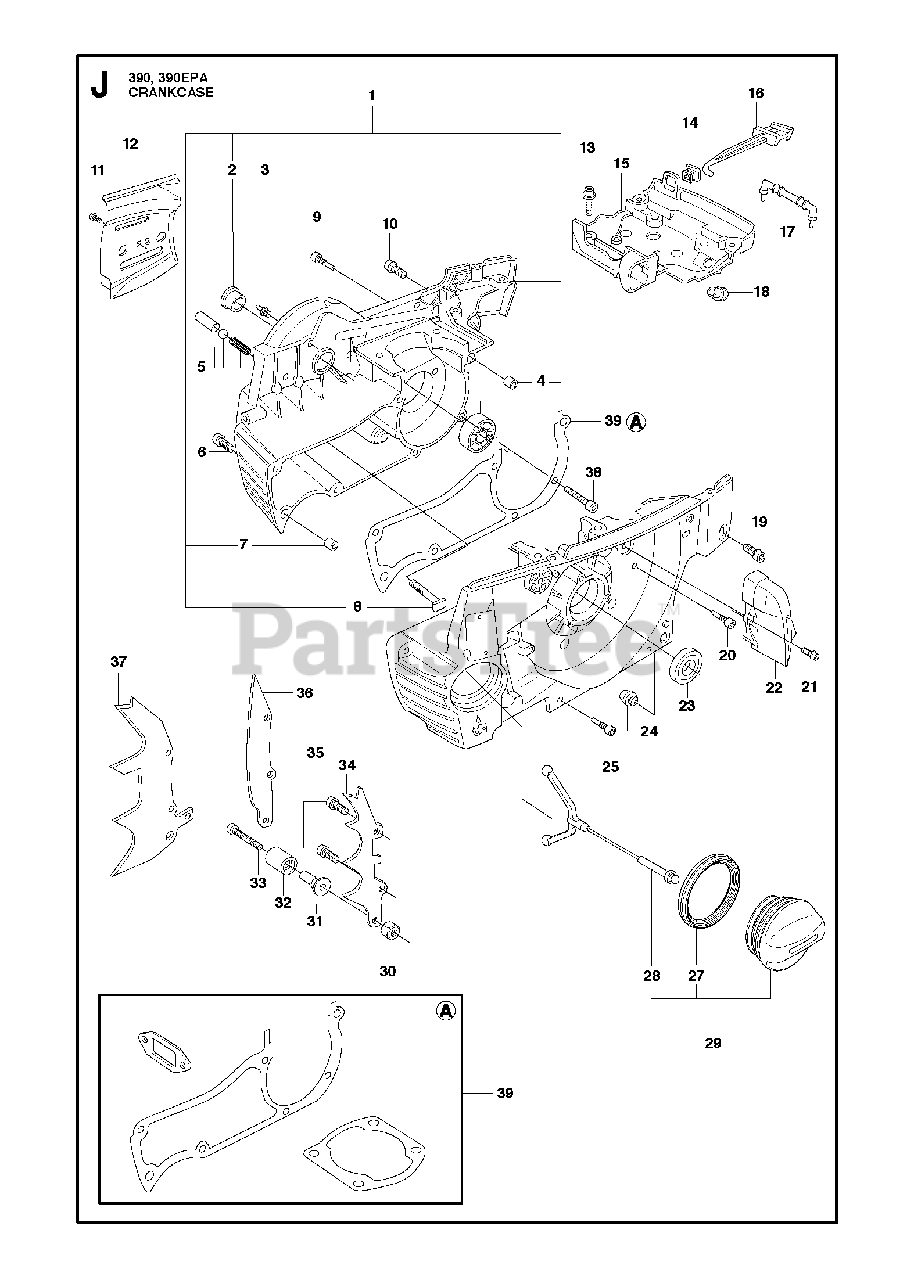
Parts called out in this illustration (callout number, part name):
2	BUSHING
3	PIN
4	SLEEVE
5	VALVE
7	SLEEVE
8	BOLT
13	SCREW
16	CHOKE CONTROL
17	SPACER
21	SCREW
23	SEALING RING
27	SEALING
28	TANK LOCK
29	TANK CAP
31	CHAIN CATCHER
34	FELLING DOG
37	FELLING DOG
39	GASKET SET
